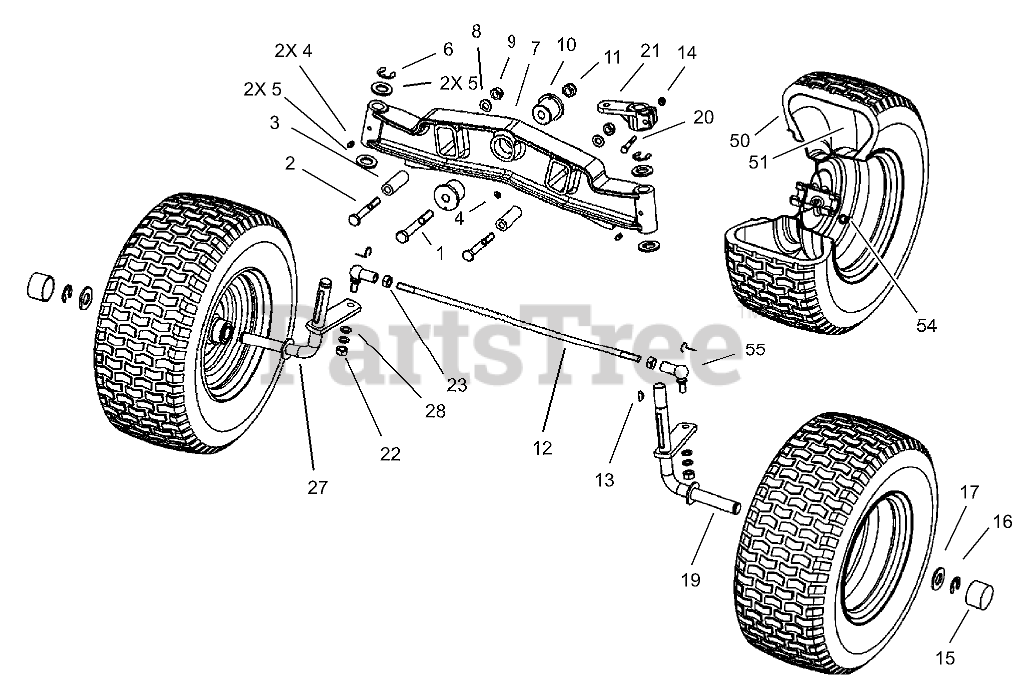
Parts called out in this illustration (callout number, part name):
1	SCREW-HH
2	SCREW-HH
3	SPACER
4	FITTING-GREASE
5	WASHER-FLAT
6	CLIP-SPRING
7	AXLE-FRONT
8	WASHER-FLAT
9	NUT-LOCK, NI
10	BUSHING-AXLE, FRONT
11	NUT-LOCKING, SELF
12	ROD-TIE, FRONT AXLE
13	KEY-WOODRUFF
14	NUT-LOCK
15	CAP-HUB
16	CLIP-SPRING
17	WASHER
19	SPINDLE-LH
20	SCREW-HH
21	LEVER-SPINDLE, STEERING
22	NUT-HEX
23	NUT-HEX
27	SPINDLE-RH
28	Washer
50	TYRE -TURF SAVER, 2-PLY
54	VALVE-TYRE
55	JOINT-BALL, ANGLE
